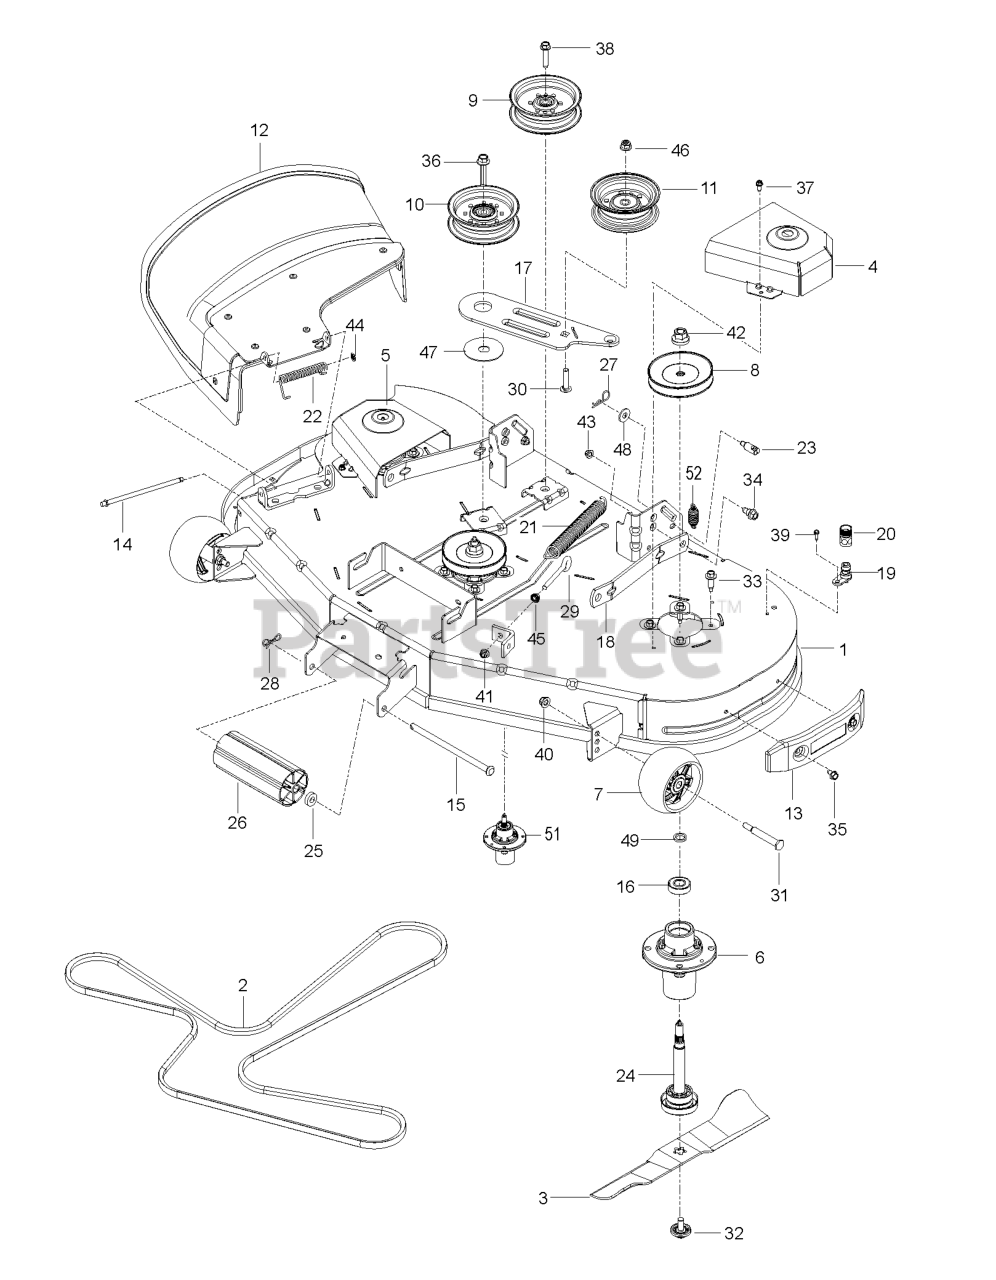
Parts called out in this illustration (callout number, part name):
1	DECK SVC.48.CC.RZ 668
3	BLADE.BAGGER.RES.CLRCT.48".BLK
4	COVER.PNT.MANDREL.LH.ZTR.GREY
5	COVER.PNT.MANDREL.RH.GREY
6	MANDREL, HOUSING - CAST IRON
6	MANDREL.DECK.ASSEMBLY
7	WHEEL.GAUGE.RALLY
8	MANDREL.PULLEY.38.BRIGHT.ZINC
9	PULLEY.IDLER.2006
9	BELT SHIELD - L.H. ORANGE
10	PULLEY.IDLER.MWR.STATI.LH
11	PULLEY.IDLER.48"PRIMARY
12	DEFLECTOR.ASM.48".CLRCT.RES.OR
13	BUMPER 48 CLEARCUT TRIM SIDE A
13	BUMPER.ASM.SIDE.TRIM.CLRCUT.48
14	ROD.HINGE
15	ROD.ROLLER.NOSE.NARROW.48"
17	ARM.PNT.CLUTCHING.EDIP
18	ARM.RFIXED.MOWER.SUSPNSIONX431
19	PORT.WASHOUT
20	COUPLING.QUICK CONNECT
21	SPRING.EXTENSION
22	SPRING.42.FCS.DEFLECTOR
23	STUD.FASTNER.W/ANTI-ROTATE
24	SHAFT ASM MANDREL
25	BUSHING.NOSE.ROLLER
26	NOSE ROLLER 48"
27	HAIRPIN #4
27	PIN.COTTER.7/16.BOW TI.
28	PIN.COTTER.5/16.BOW TI
29	EYE BOLT 5/16 X 3.50
31	Bolts
31	BOLT.SHOULDER.3/8-16X3-5/8.
32	BOLT.WASHER.ASM.7/16-2
33	BOLT.HEX.WASHR.HED.313-18X1.19
34	BOLT.SHOULDER
35	SHOULDER BOLT 5/16-18TT
36	SCREW.7/16-14 X 2.125.WASHER
37	SCREW.1/4-20X5/8
38	SCREW LT
39	SCR 1/4-20X5/8 HEX SELF TAP ZD
40	NUT 3/8-16 HEX FLG NYLOC ZD
41	NUT HEXAGON FLANGE 5/16-18 ST
41	5/16-18 NYLOC FLANGE NUT
42	NUT.FLANGE.LOCK.TOP
42	BOLT.SHOULDER.3/8-16X3-5/8.
43	GSPW Nuts
43	NUT LOCK HEX FLANGE 5/16-18
44	NUT PUSH M
45	NUT 5/16C WHIZ
46	NUT LOCK FLG 3/8-16 UNC
46	LOCKNUT
48	WASHER
49	WASHER.SPACER.MANDREL
51	MANDREL ASM, CAST IRON
52	Springs
